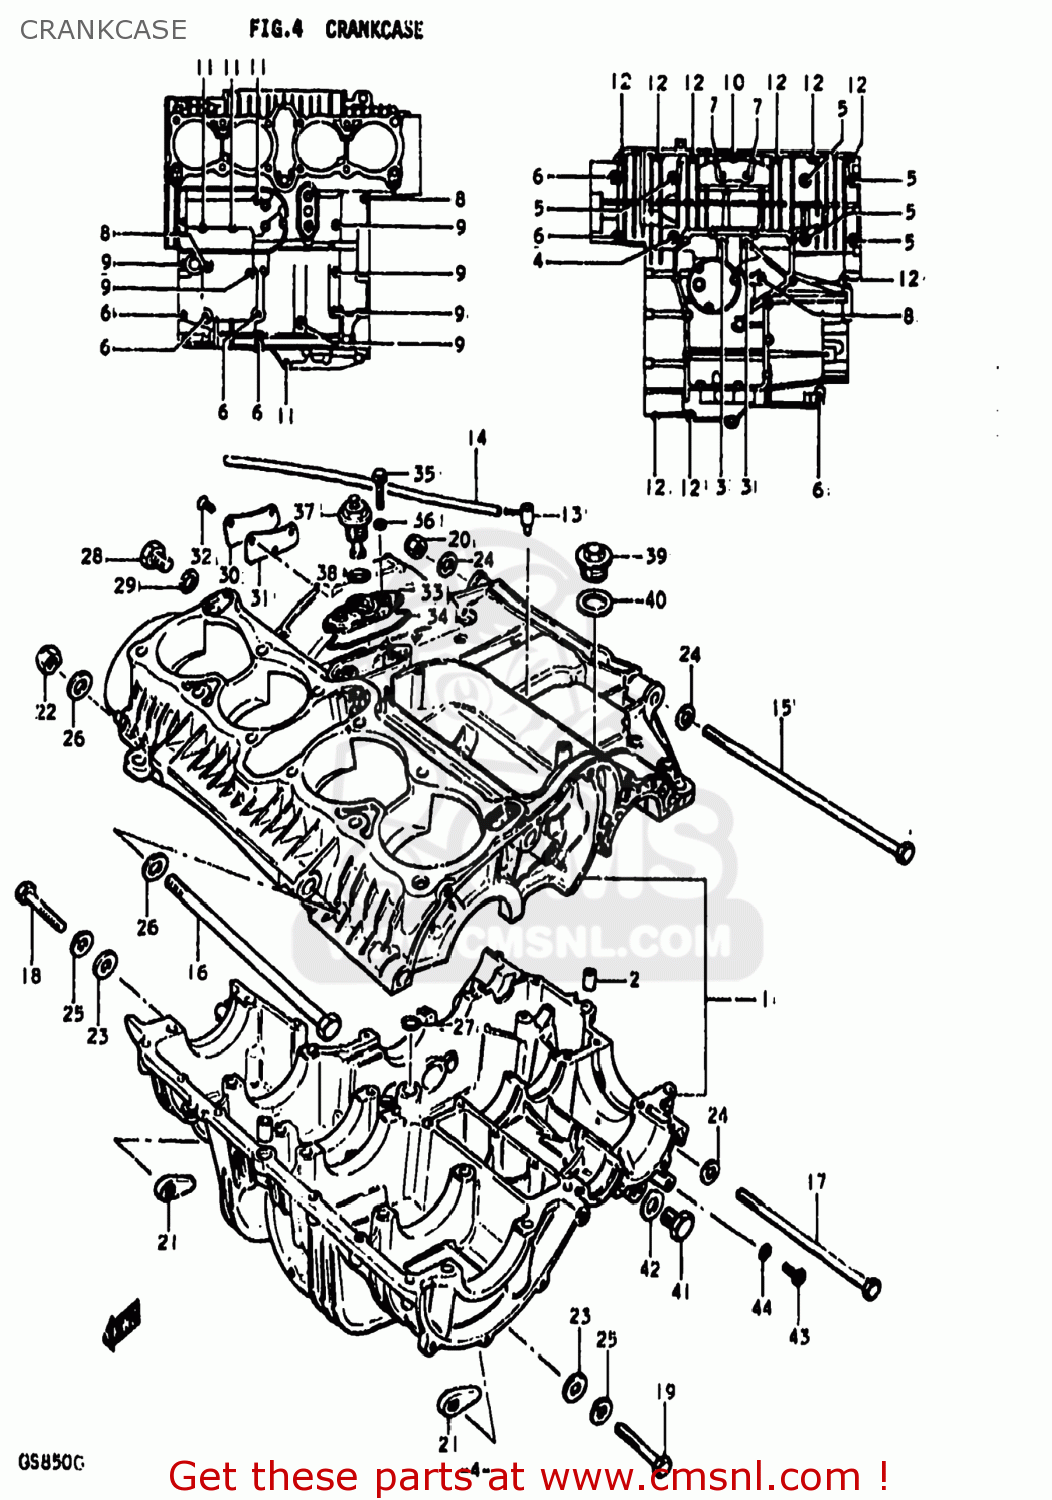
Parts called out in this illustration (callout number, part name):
1	CRANKCASE SET
2	PIN
3	BOLT
4	BOLT
5	BOLT 8X90
6	BOLT 8X65
7	BOLT
8	BOLT (6X90)
9	BOLT (6X75)
10	BOLT ,6X50
11	BOLT,UNDER
12	BOLT 6X35
13	BPLUG,BEVEL GEAR BREATHER
14	HOSE
15	BOLT 10X270
16	SHAFT,REAR SWING ARM
17	BOLT(10X165)
18	BOLT 10X60
19	BOLT (10X50)
20	NUT
21	NUT
22	NUT 12MM
23	WASHER(10.5X20X3.2)
24	WASHER
25	LOCK WASHER
26	WASHER
27	O RING(D:3.2,ID:12.9)
28	PLUG (14X12)
29	GASKET(14X19.2X2) (NAS)
30	CAP,OIL GALLERY
31	GASKET,OIL GALLERY (MCA)
32	SCREW
33	HOUSING,OIL PRESSURE SWITCH
34	O RING,PRESSURE SWITCH HOUSING
35	BOLT
36	GASKET (NAS)
37	SWITCH ASSEMBLY
38	O RING(D:1.9,ID:18.8)
39	PLUG
40	GASKET (NAS)
41	PLUG
42	GASKET(14X19.2X2) (NAS)
43	SCREW(6X10)
44	GASKET (NAS)
